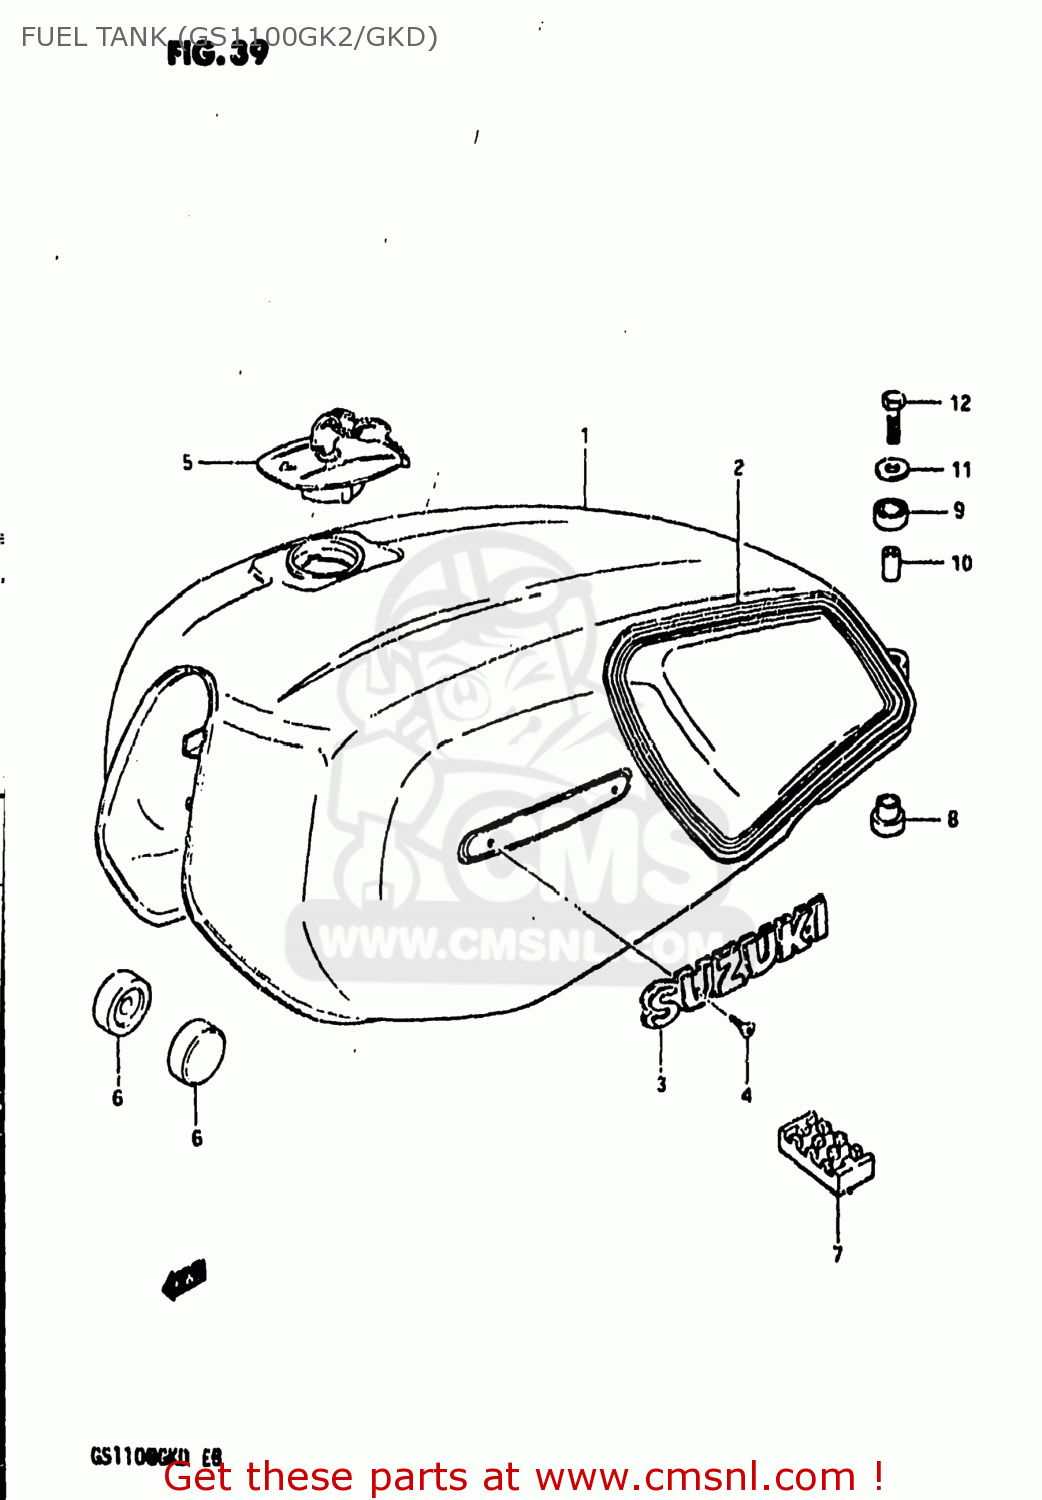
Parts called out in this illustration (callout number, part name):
1	TANK ASSEMBLY,FUEL
2	TAPE SET,FUEL TANK
3	EMBLEM
4	SCREW 3X6
5	CAP SET,FUEL TANK
6	CUSHION
7	CUSHION,FUEL TANK
8	CUSHION
9	CUSHION
10	SPACER (6.4X9X21.5)
11	WASHER (6.5X24X1.6)
12	BOLT
